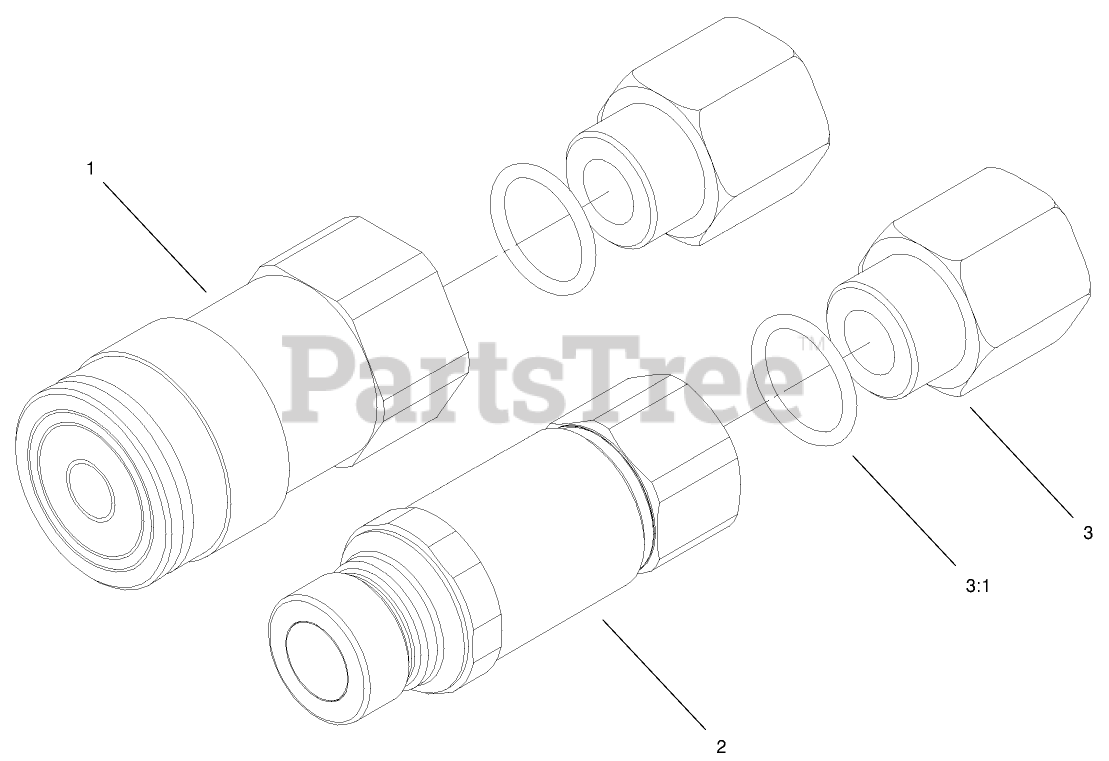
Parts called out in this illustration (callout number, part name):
1	COUPLER-FACE, FLUSH
2	NIPPLE-CONNECT, PRESSURE
3	ADAPTER-HYD
3:1	O-RING
